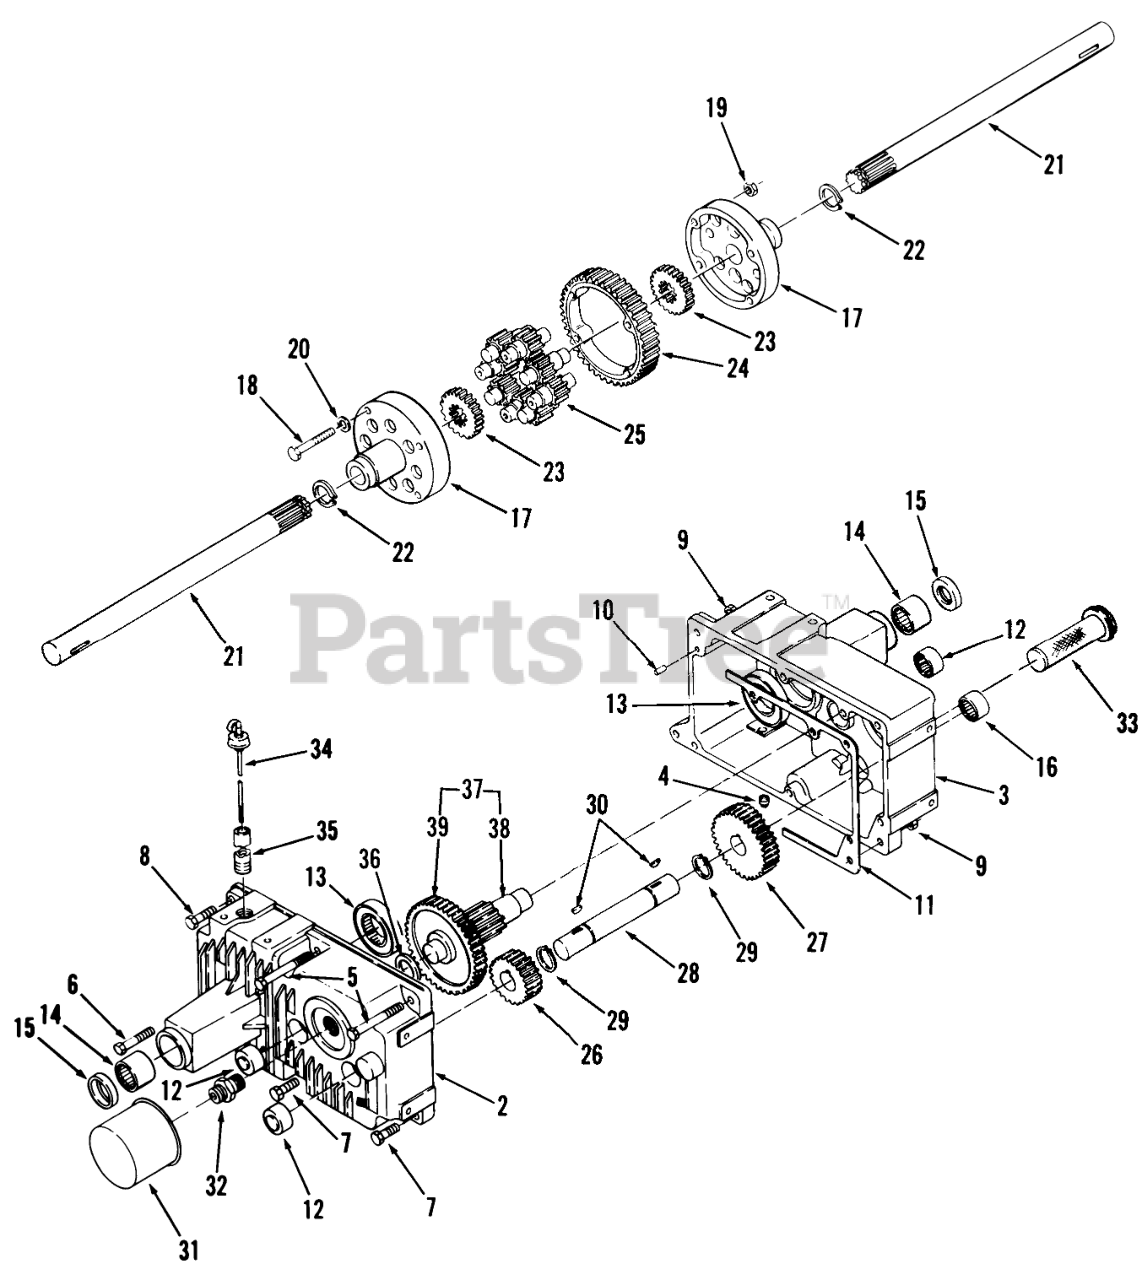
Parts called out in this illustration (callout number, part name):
1	Transaxle Complete
2	Case RH
3	CASE-AUTOMATIC LH
4	PLUG 1/4 PIPE ALLEN
5	H H C S
6	HHCS
7	Bolt
8	Bolt
9	Nut
10	PIN-DOWEL
11	GASKET
12	BEARING-NEEDLE
13	BALL BRG 1 1/2 I.D.
14	BEARING
15	SEAL-OIL
16	Needle Bearing
17	DIFFERENTIAL END CAP
18	BOLT-HEX
19	Nut
20	WASHER
21	AXLE-REAR
22	RING-SNAP
23	GEAR-AXLE DIFFERENTIAL
24	GEAR-DIFFERENTIAL RING, 43T
25	GEAR-PINION, 11T
26	GEAR 24T
27	Gear 44T
28	SHAFT GEAR
29	Snap Ring
30	Key
31	Filter
32	FITTING
33	STRAINER
34	ASSY-DIPSTICK
35	NIPPLE-TRANS FILL
36	WASHER-THRUST
37	GEAR ASSY
38	PINION SHAFT
39	Gear-42T
